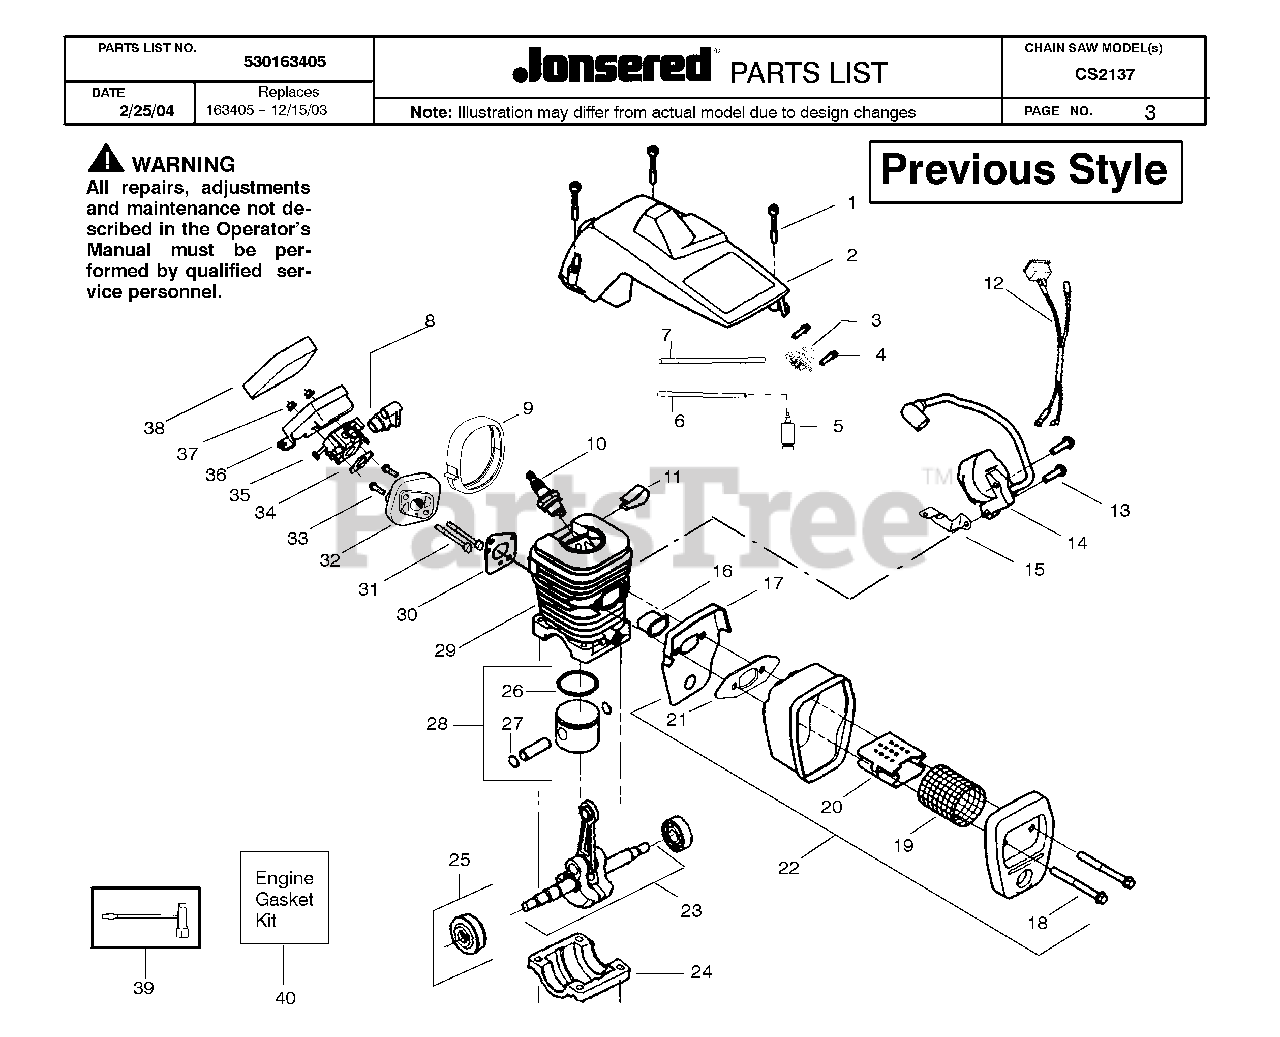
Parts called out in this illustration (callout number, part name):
2	CYL SHIELD ASSY
5	FUEL PICK-UP ASSY
8	GROMMET-CARB ADJUST
10	SPARK PLUG (RCJ-7Y)
12	WIRE HARNESS ASS'Y
14	MODULE-IGNITION
15	GROUND STRAP
16	HEAT INSULATOR
20	FLAME PROTECTION
22	MUFFLER
23	CRANKSHAFT
25	BEARING & SEAL ASSEMBLY
26	RING-PISTON
27	C-CLIP,PSTN PIN 36/41
29	KIT-CYLINDER
32	PARTITION
38	AIR FILTER
39	SCRENCH
530038317	LIMITER CAP (LOW-BLUE)
530047630	DECAL STOP
530069722	CARBURETOR
530071621	KIT-CARBURETOR (WT-625)
